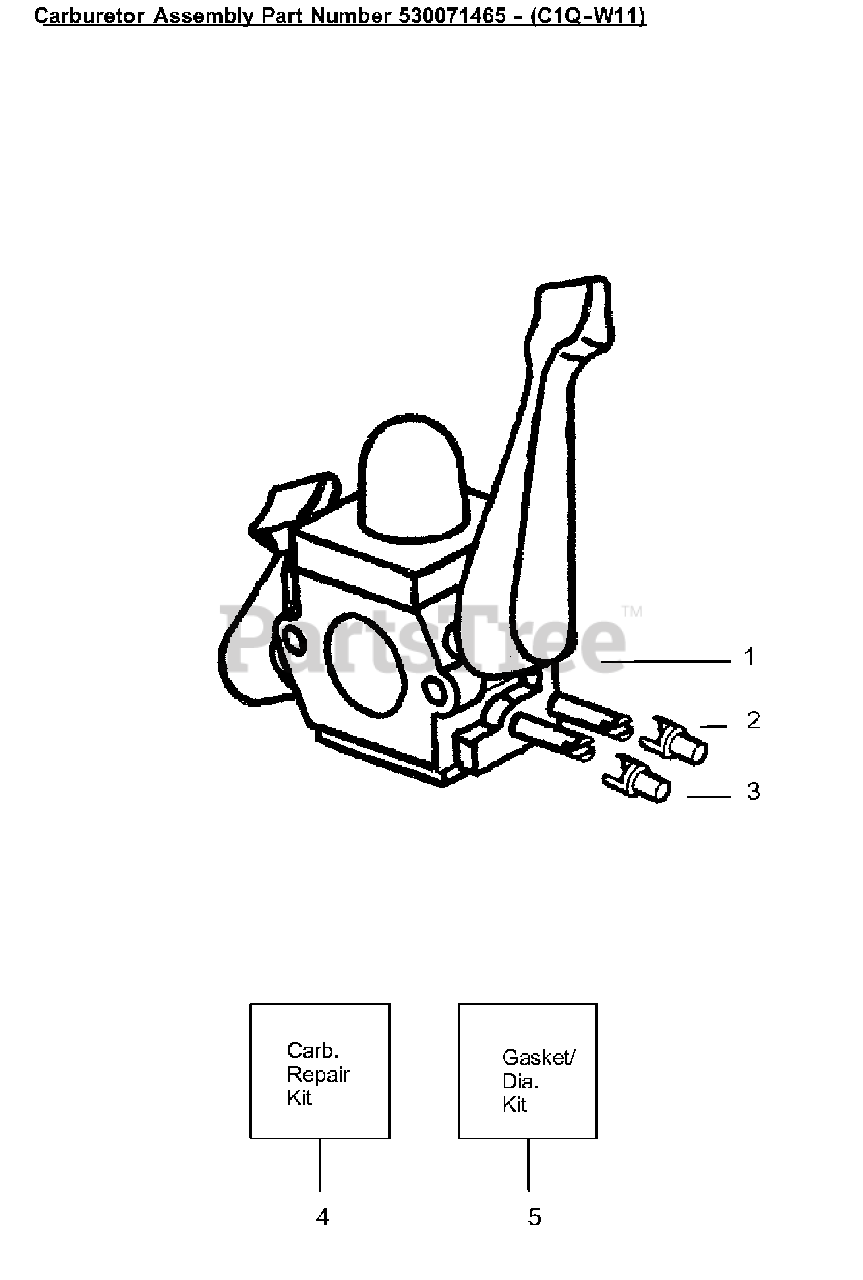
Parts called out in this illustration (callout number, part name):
1	Assy-Carb. Zama (C1Q-W11)
2	Cap-Limiter (high) brown
3	Cap-Limiter (low) tan
4	Kit-Carb. Repair
5	Kit-Dia. (GND-34)
